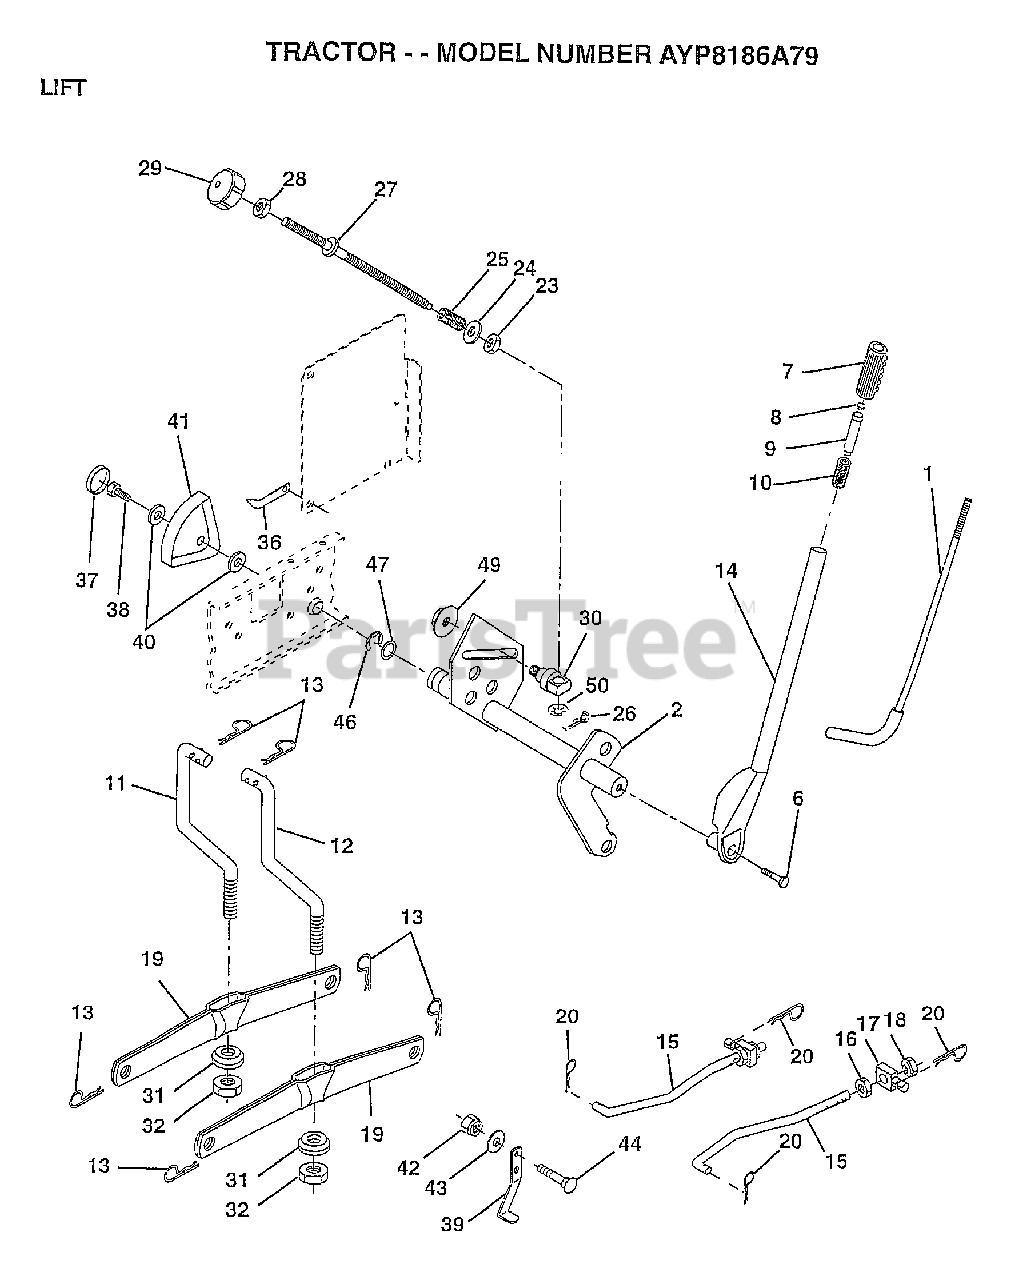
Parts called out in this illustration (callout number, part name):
1	LEVER ROD LT
2	SHAFT LIFT W/IND
6	"BOLT,HEX"
7	GRIP
10	SPRING T
11	LINK.LIFT.LH.GTV
12	LINK.LIFT.RH.GTV.
15	LINK.FRONT
16	NUT
17	TRUNION
18	NUT.LK.W/WSH.1/2.
19	ARM SUSP REAR
20	RETAINER.SPRING
23	NUT T
24	WASHER
25	SPRING T
28	NUT
29	KNOB INF 3/8-16
30	TRUNNION
31	BEARING PVT LH
32	NUT.CROWNLOCK.3/8
36	POINTER-INDICAT
37	"PLUG,HOLE"
38	SCREW
39	STOP.OVER.CENTER
40	WASHER
41	HEIGHT INDICATOR
43	WASHER GT
44	BOLT
46	E-RING
47	WASHER
49	NUT.HXFLG.LOCK.
50	NUT PUSH M
